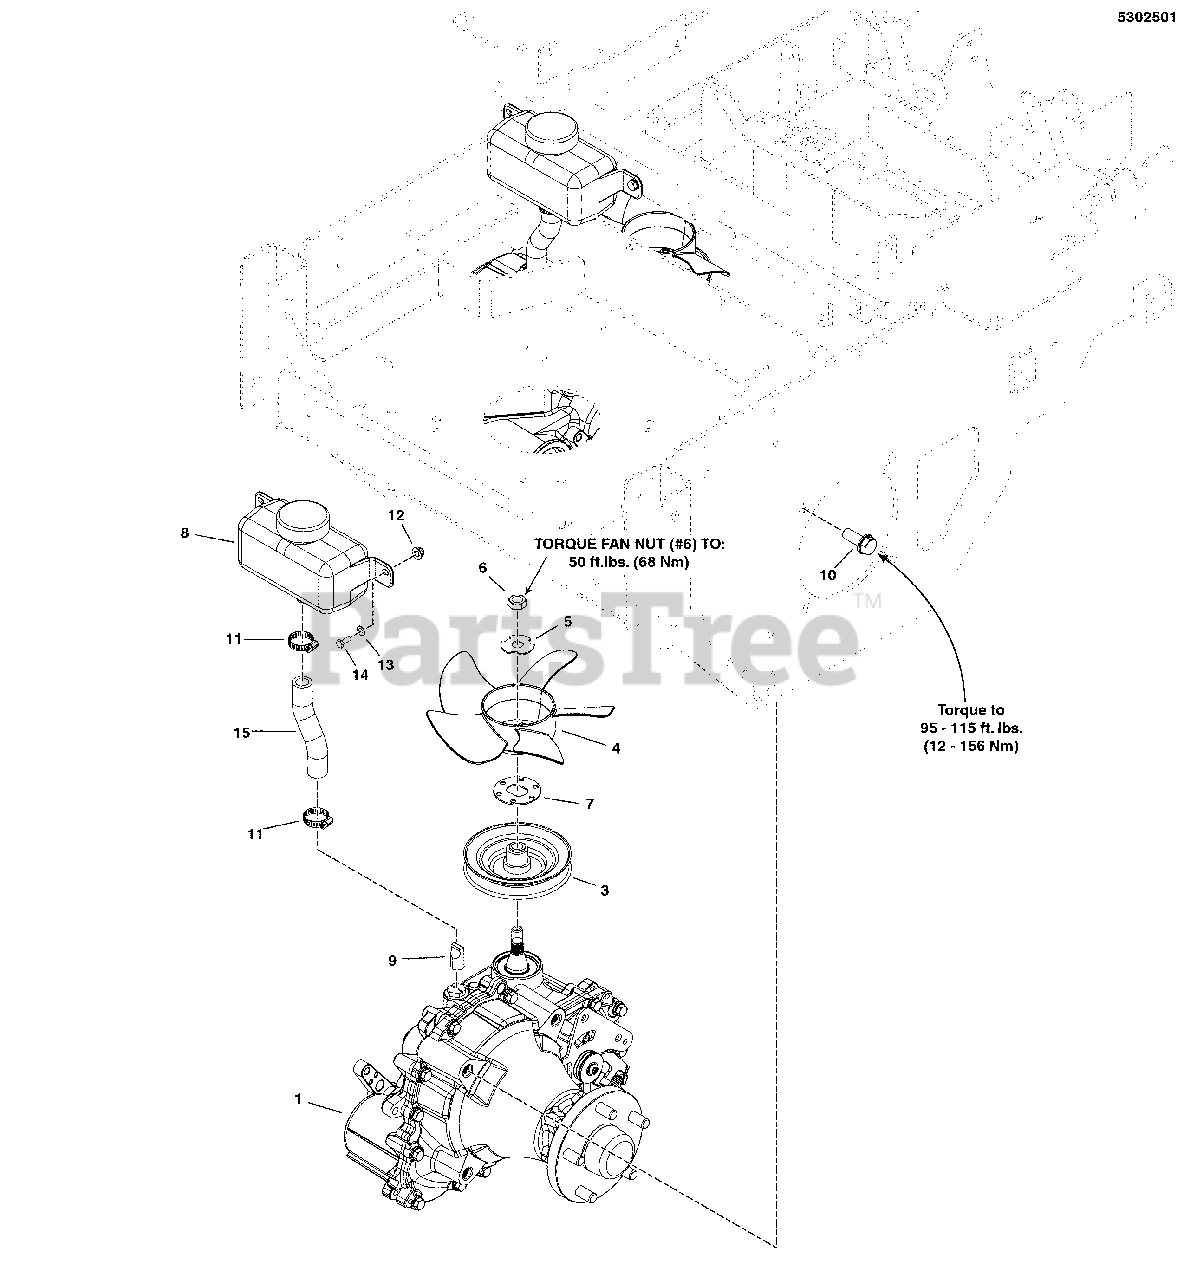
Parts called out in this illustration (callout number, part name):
1	TRANSAXLE, ZT5400, RH, 1015-1024R
2	TRANSAXLE, ZT5400, LH, 1015-1024L
3	PULLEY, ZT5400 (53179)
4	FAN, ZT5400
5	WASHER, ZT5400, SLOTTED
6	NUT, ZT5400
7	SPACER, ANTI ROTATE, ZT5400
8	HYDRO TANK, HYDRO-GEAR 71938, 1 LITER
9	FITTING, BREATHER, ZT5400
10	BOLT,HEX FLG,SER,GD8 1/2-13X1-1/4W/PATCH
11	CLAMP, #10 HOSE, STAINLESS
12	NUT, 1/4-20 HEX NYLOCK FLANGE
13	WASHER, 1/4 SAE
14	BOLT, 1/4-20 X 3/4 GD5 YZ
15	HOSE, OFFSET FORMED
